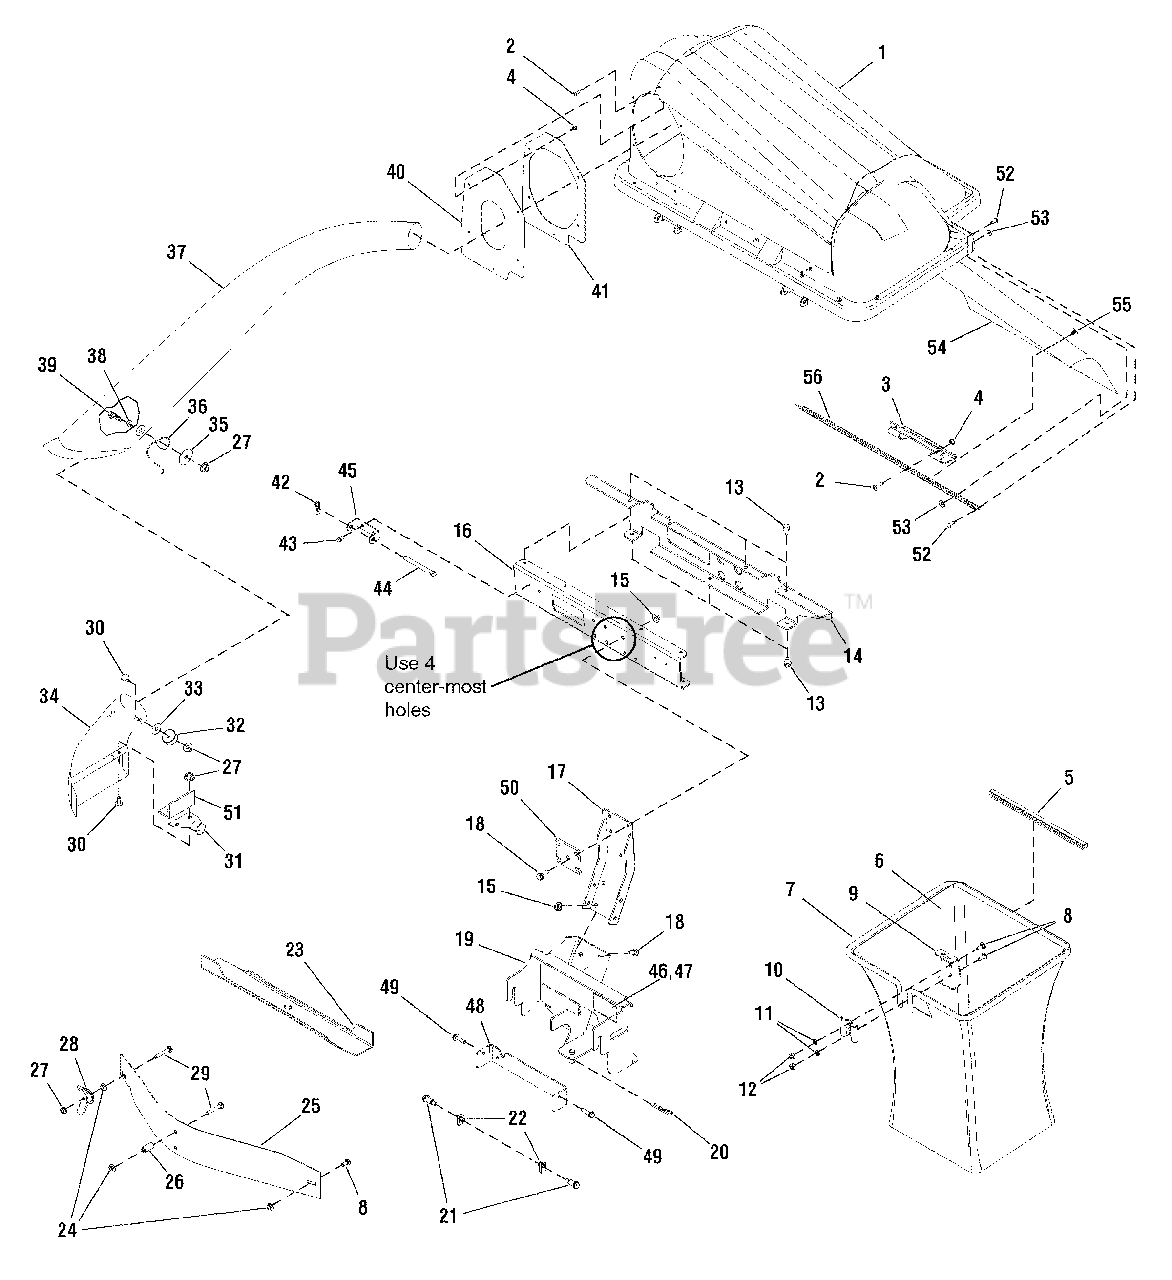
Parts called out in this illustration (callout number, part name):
1	COVER ASSEMBLY, Twin Catcher
2	SCREW, Truss Head Phillips, 10 - 24 x 3/4
3	HANDLE, Plastic
4	NUT, Hex Lock w/Nylon Insert, 10 - 24
5	CLIP, Tube Grass Bag
6	BAG, Grass White Poly
8	BOLT, Carriage, 5/16 - 18 x 3/4
9	HANGER, Grass Bag
10	CLAMP, Grass Bag Plain
11	LOCKWASHER, Spring, 5/16
12	NUT, Hex, 5/16 - 18
13	SCREW, Hex Washer Head Taptite, 5/16 - 18 x 3/4
14	BRACKET, Tab Cross Support Twin
15	NUT, Hex Whiz Lock Flange
16	CHANNEL, Cross Support Twin
17	SUPPORT, Upright
18	SCREW, Hex Whiz Lock Flange
19	SUPPORT ASSEMBLY, Regent Catcher
20	CLIP, Hair Pin
21	BOLT, Shoulder, 5/16 - 18
22	NUT, Speed, 5/16 - 18
23	BLADE, Mower 22.3" Hi-Lift
24	NUT, Hex Whiz Lock Flange, 5/16-18
25	BAFFLE, 38"
26	SPACER
27	NUT, Hex Two-Way Lock Flange, 5/16 - 18
28	WINGNUT ASSEMBLY
29	BOLT, Carriage, 5/16 - 18 x 2
30	SCREW, Hex Head, 5/16 - 18 x 3/4
31	BRACKET, Offset
32	WASHER, Special
33	WASHER
34	ADAPTER, 38"
35	WASHER, 5/16
36	LATCH, Tube
37	TUBE, Transfer
38	WASHER, 5/16
39	SCREW, Hex Head, 5/16 - 18 x 3/4
40	SEAL, Cover
41	FLANGE, Seal
42	CLIP, Hair Pin
43	SCREW, Hex Washer Head Taptite, 1/4 - 20 x 1/2
44	PIN, Cover Hinge
45	PIVOT, Hinge
46	ID LABEL/SERIAL PLATE
47	OVERLAY, Mylar
48	PLATE, Reinforcement
49	SCREW, Hex Whiz Lock Flange, 5/16 - 18 x 1-1/4
50	PLATE, Reinforcement, Upright
51	BRACKET, Deflector Prop
52	RIVET, Pop, 3/16
53	WASHER, Rivet, 3/16
54	SCREEN, Twin Cover
55	FASTENERS, Push, 1/4 x 1/2
56	SCREEN SUPPORT, Twin
